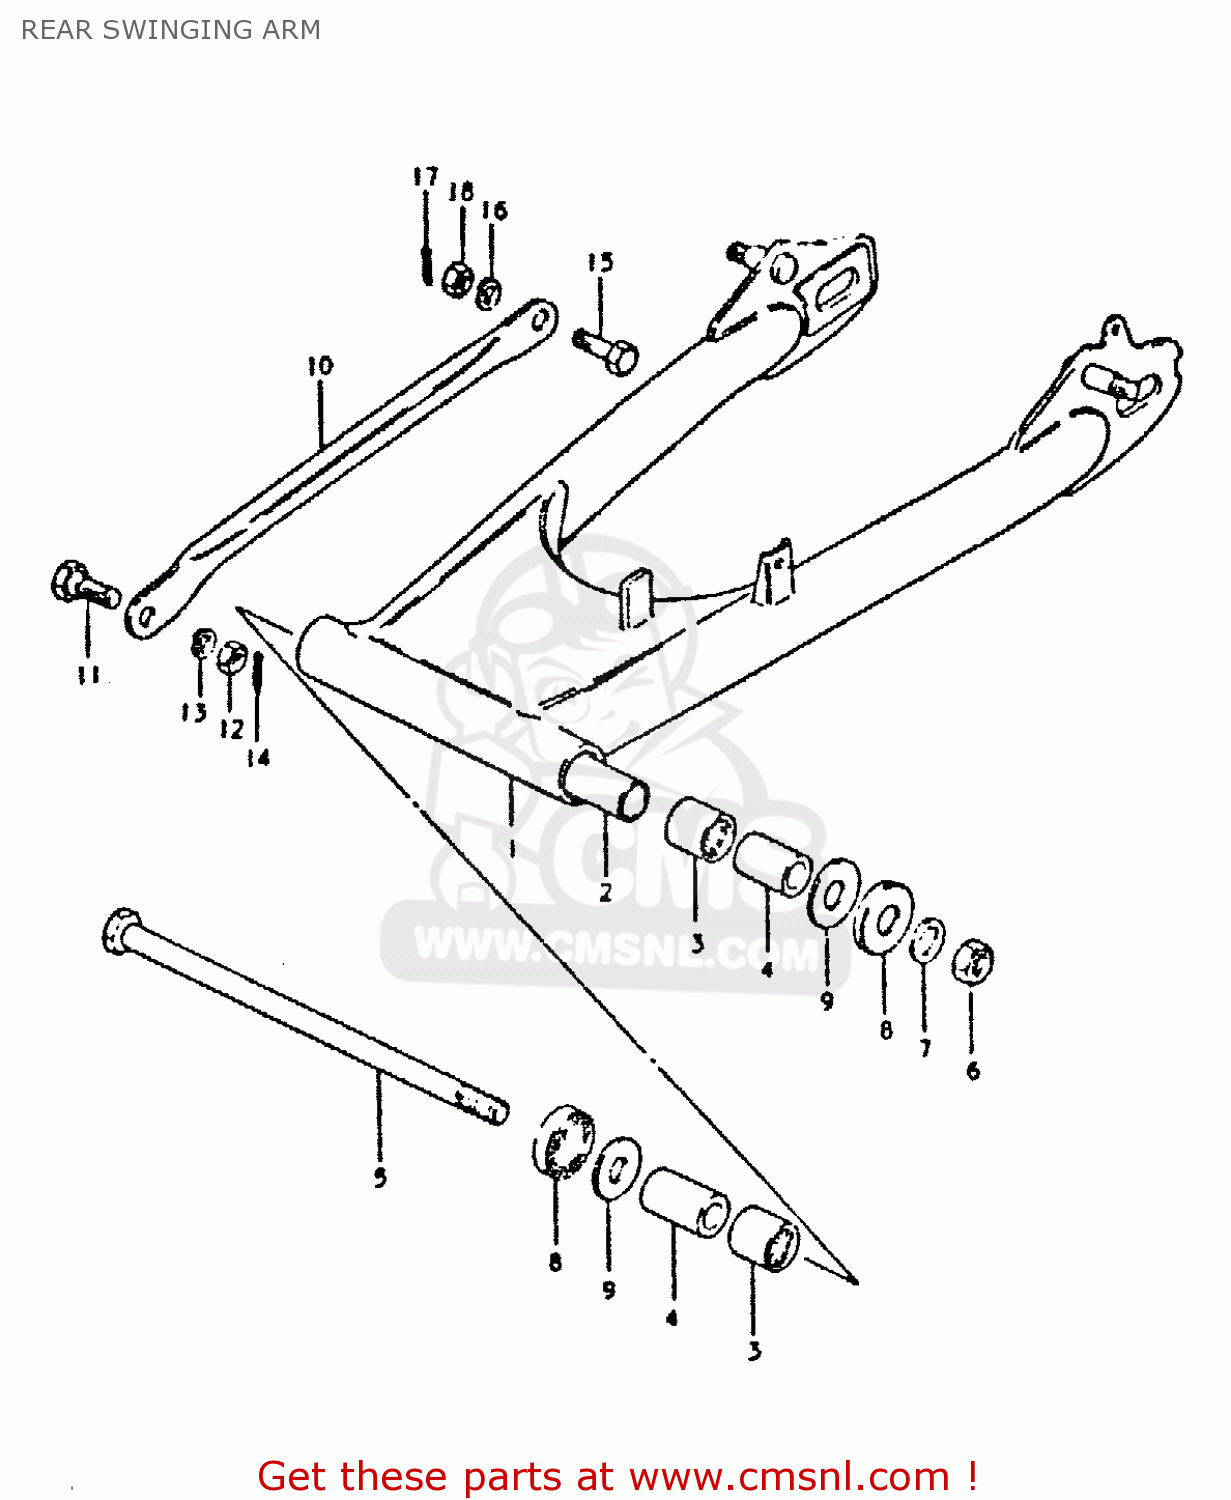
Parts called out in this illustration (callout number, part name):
1	SWING ARM ASSEMBLY,REAR
2	SPACER,SWINGINGARM CTR
3	BEARING(22X29X30)
4	SPACER,RR SWGARM PIVOT
5	SHAFT,REAR SWING ARM
6	NUT 14MM
7	WASHER
8	COVER,REAR SWING ARM DUST
9	WASHER(14.2X34X1)
10	TORQUE LINK,REAR
11	BOLT(10X24.5)
12	NUT
13	LOCK WASHER
14	PIN
15	BOLT(10X31)
16	LOCK WASHER
17	PIN
18	NUT
